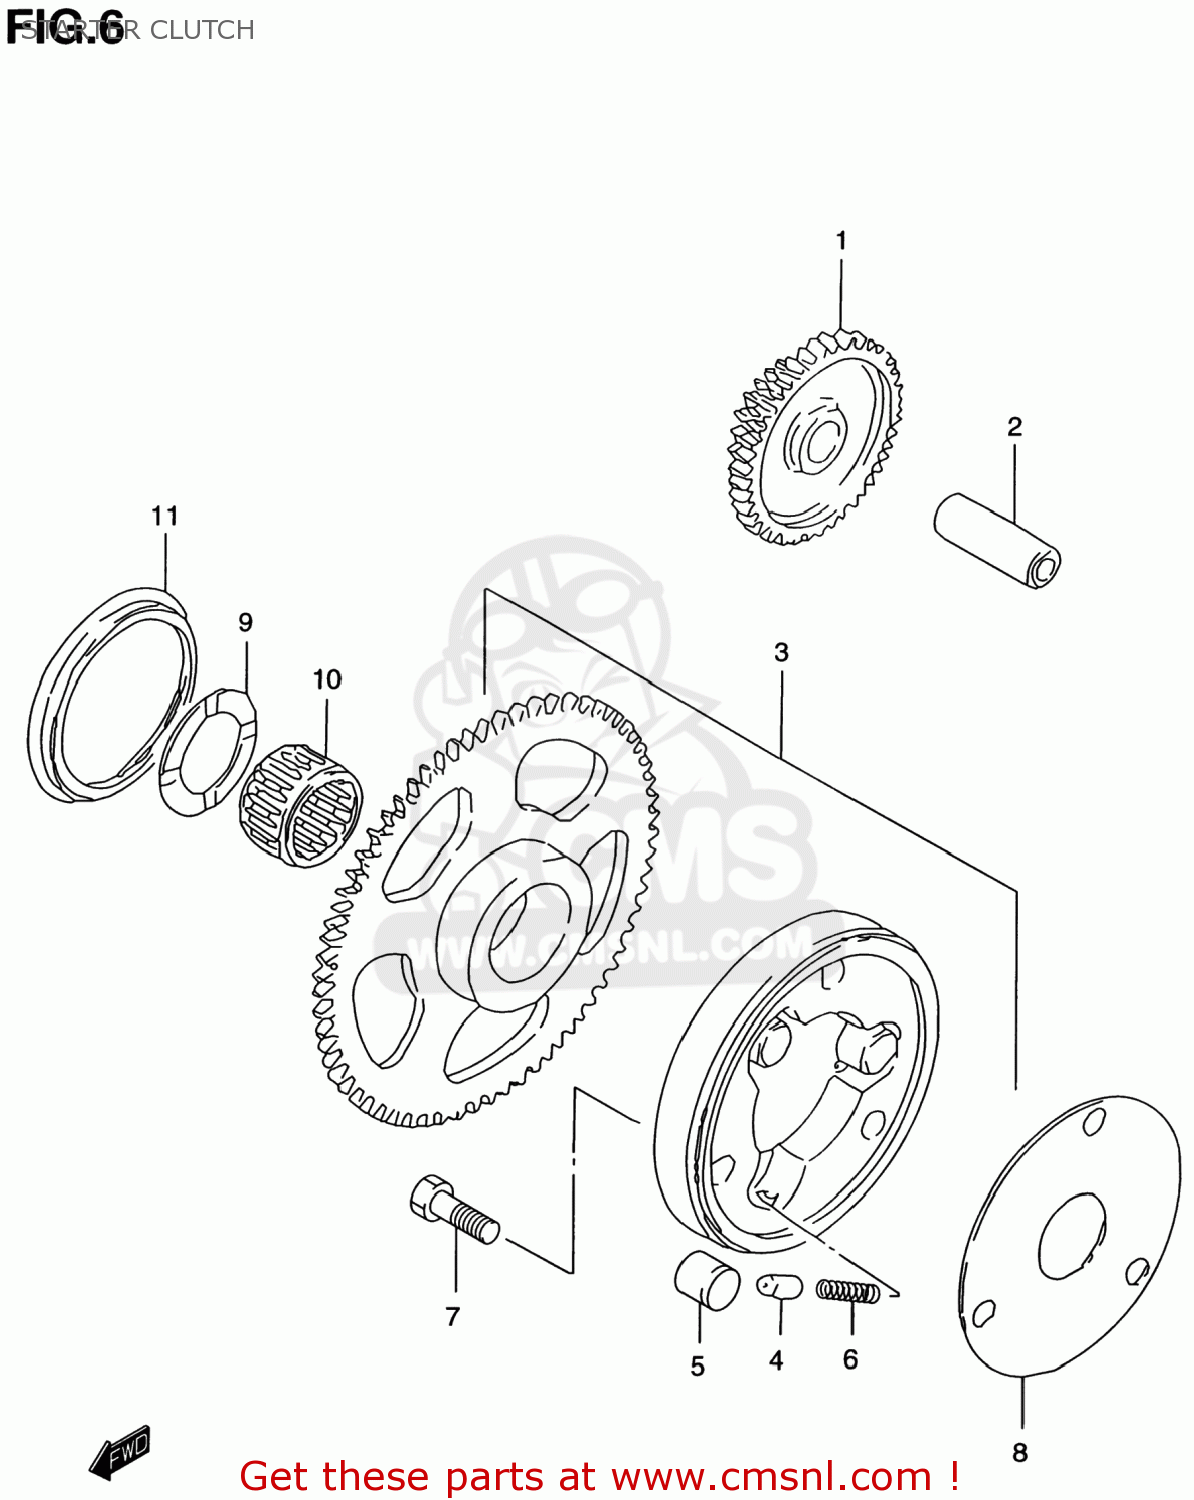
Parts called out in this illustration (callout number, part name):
1	GEAR,STARTER IDLE
2	PIN(7.4X13X40)
3	CLUTCH SET,STARTER
4	PIECE,PUSH
5	PIN(14X13)
6	SPRING
7	BOLT
8	SHIM,STARTER CLUTCH HUB
9	WASHER(27X40X2.5)
10	BEARING(27X32X21.8)
11	SEAL,OIL(52X62X6.8)
